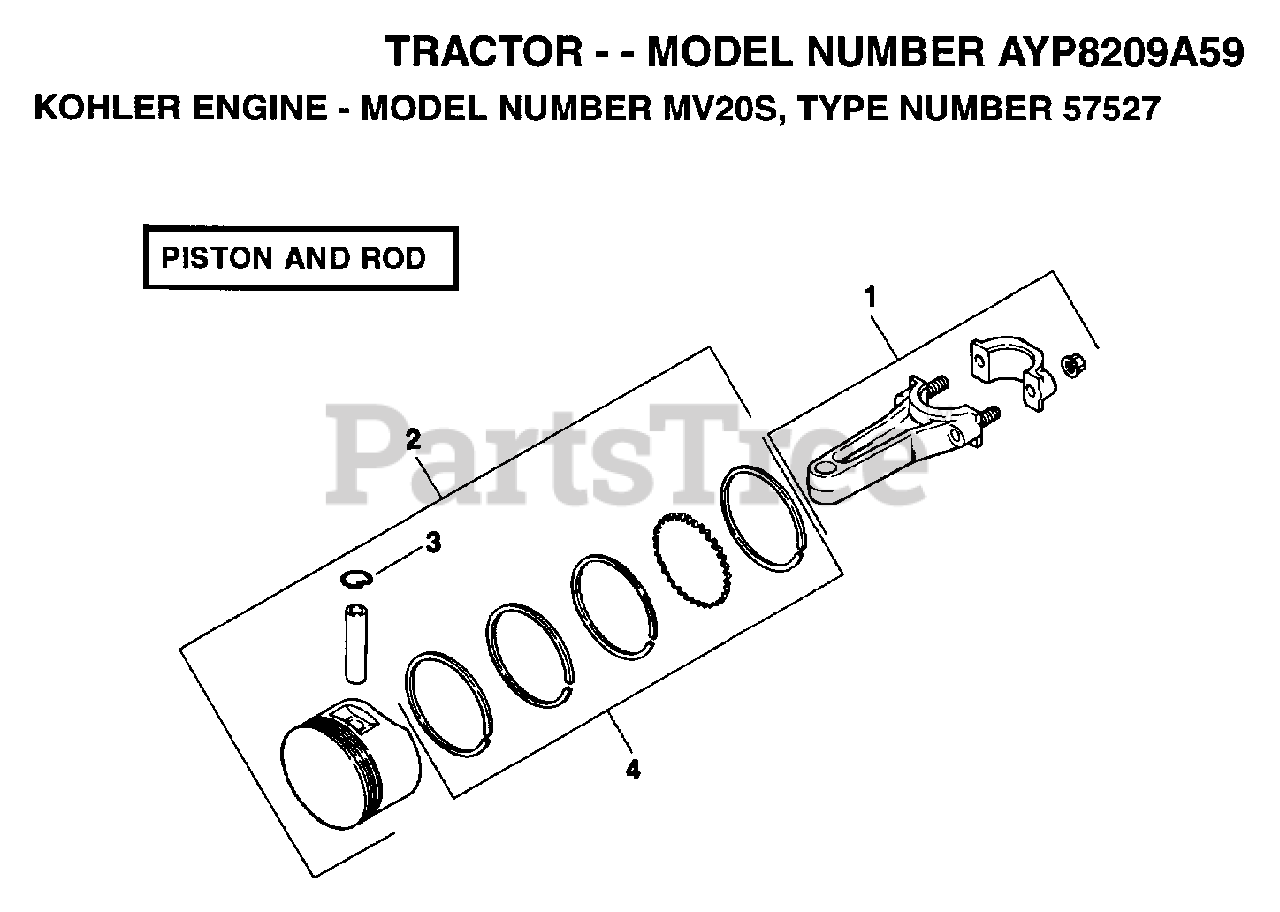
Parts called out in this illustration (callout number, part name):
1	CONNECTING ROD, STANDARD
2	PISTON WITH RING SET, STANDARD
3	RETAINER, PISTON PIN
4	RING SET, .003"
